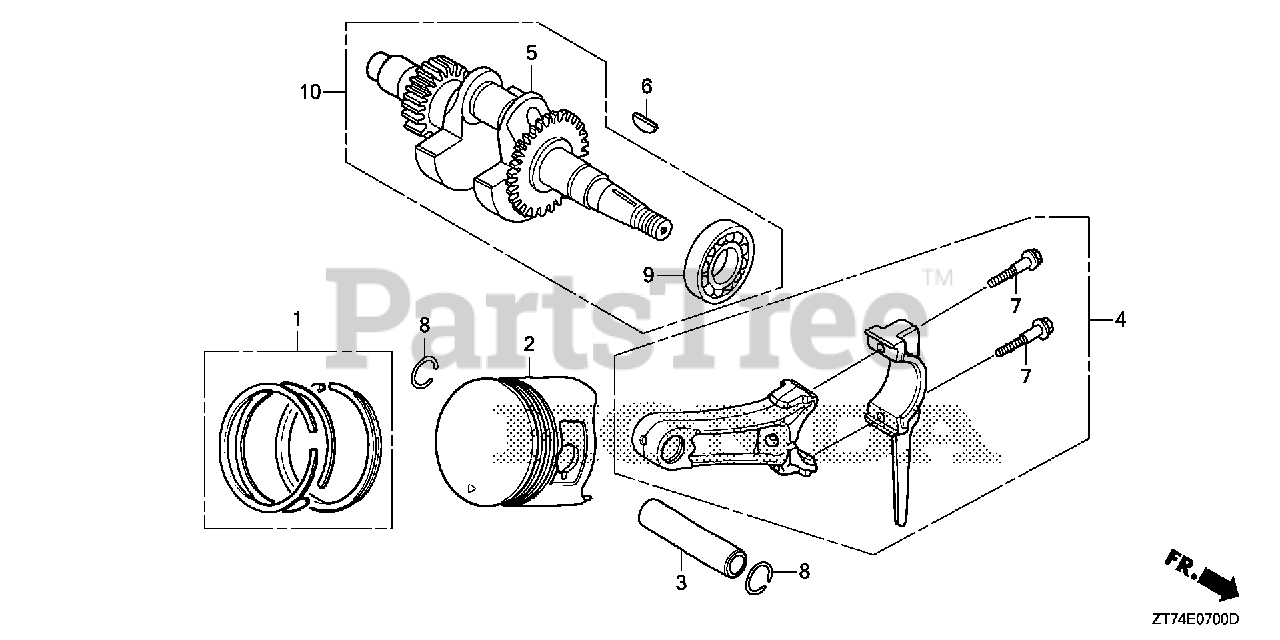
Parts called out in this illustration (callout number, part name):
1	RING SET, PISTON (STD) (TPR)
1	RING SET, PISTON (0.25) Use from Engine SN 1314913.
1	RING SET, PISTON (0.50) (TPR)
1	RING SET, PISTON (0.75) Use from Engine SN 1314913.
1	RING SET, PISTON (STD) (RIKEN)
1	RING SET, PISTON (0.25) (RIKEN)
1	RING SET, PISTON (0.50) (RIKEN)
1	RING SET, PISTON (0.75) (RIKEN)
2	PISTON (STD)
2	PISTON (0.25)
2	PISTON (0.50)
2	PISTON (0.75)
3	PIN, PISTON
4	ROD ASSY., CONNECTING
4	ROD ASSY., CONNECTING (UNDER SIZE) (NOT AVAILABLE)
6	KEY, SPECIAL WOODRUFF (25X18)
7	BOLT, CONNECTING ROD
8	CLIP, PISTON PIN (18MM)
9	BEARING, RADIAL BALL (6205)
9	BEARING, RADIAL BALL (6205) (NSK)
10	CRANKSHAFT
